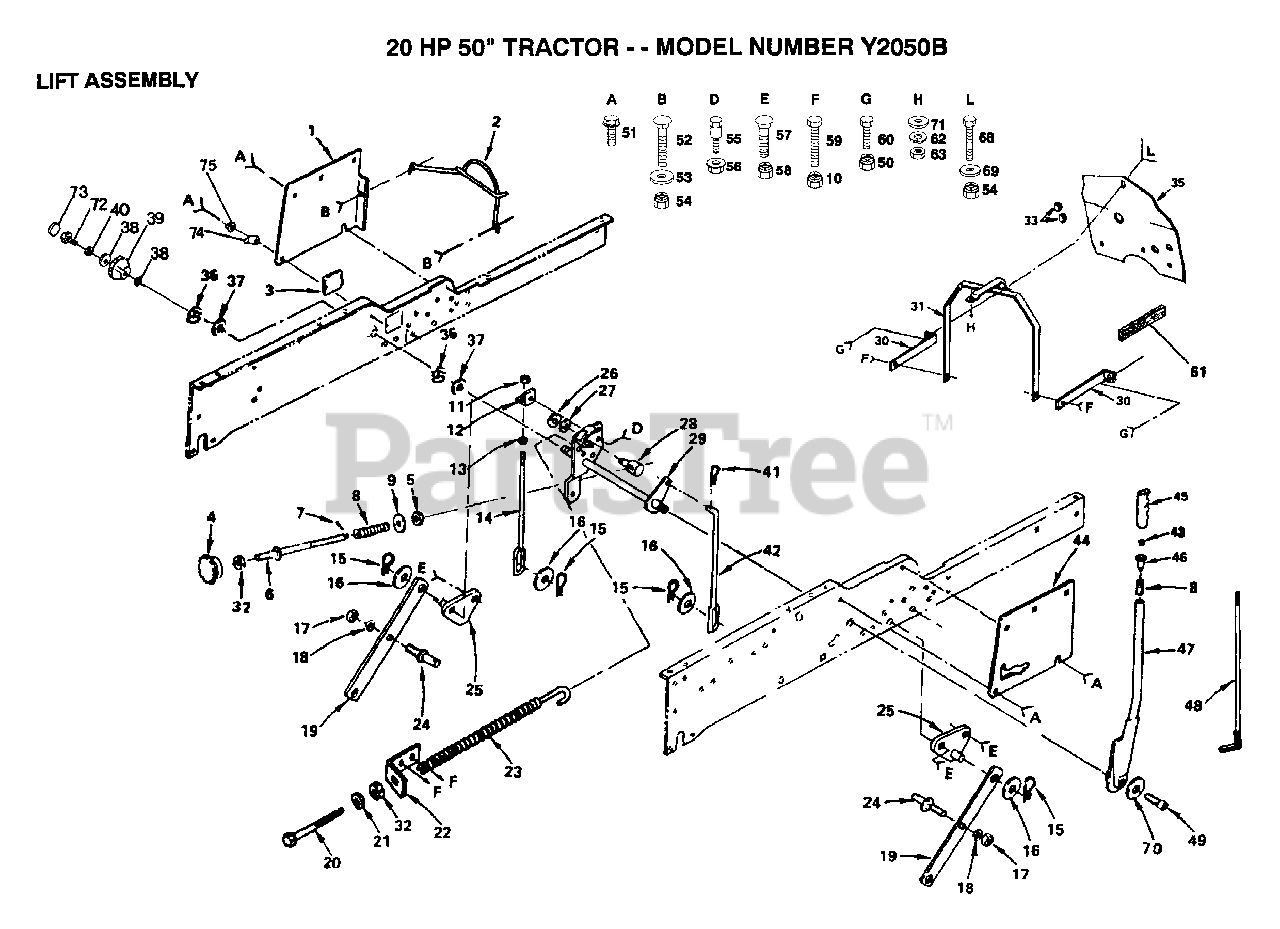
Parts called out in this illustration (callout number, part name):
2	"GUARD, BELT"
3	COVER ACCESS
4	KNOB INF 3/8-16
5	NUT T
6	ROD ADJ. T
8	SPRING T
9	WASHER
11	NUT
12	BRACKET T
13	NUT.HEX.3/8-16UNC
14	LINK-LIFT MOW T
15	SPRING H
17	NUT
18	LOCKWASHER
19	SUSPENSION ARM GT
20	BOLT-ADJ SPRING T
21	WASHER
24	PIVOT STUD GT
25	SUSP BRACKET T
26	KLIP RING
27	WASHER
28	TRUNION LT
29	SHAFT ASS'Y LIFT
30	BRACKET T
32	NUT
35	"SHIELD HEAT, BASE"
36	E-RING
37	WASHER
38	WASHER
39	HEIGHT INDICATOR
40	LOCKWASHER
42	LIFT LINK RH T
45	GRIP HANDLE
48	LEVER ROD LT
49	"BOLT,HEX"
51	SCREW LT
52	BOLT
53	WASHER
55	SHOULDER BOLT T
56	NUT T
57	BOLT
58	LOCKNUT
59	BOLT
60	BOLT
61	FOAM STRIP T
68	BOLT
69	WASHER M
70	LOCKWASHER
71	WASHER PM
73	"PLUG,HOLE"
74	POINTER HGT IND
75	WASHER T
